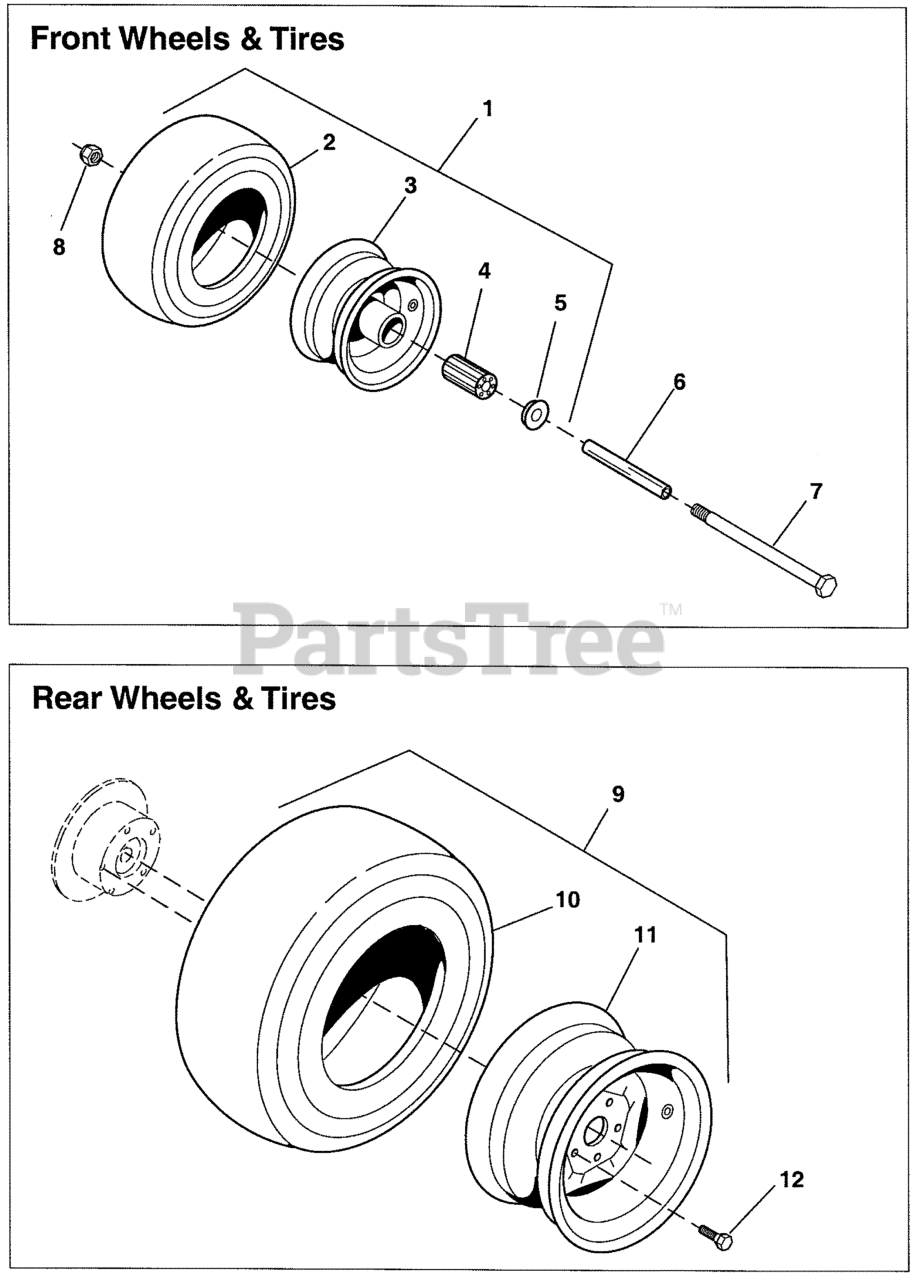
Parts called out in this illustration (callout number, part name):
1	WHEEL & TIRE ASSEMBLY, Front, 13 x 6.5 x 6, Complete
2	TIRE, RUBBER ONLY
3	WHEEL ASSEMBLY, Front, for 13 x 6.5 x 6 Tires, Complete
4	BEARING, Roller
5	RETAINER, Bearing
6	AXLE, Front Caster
7	BOLT, 1-2/13 x 8-1/2
8	NUT, 1/2-13 HEX NYLON LOCK
9	WHEEL & TIRE ASSEMBLY, Rear, 24 x 12 x 12, Complete
10	TIRE, Rear, 24 x 12 x 12
11	WHEEL ASSEMBLY, Rear, for 24 x 12 x 12 Tires
12	WHEEL LUG, 1/2 x 1-5/8
